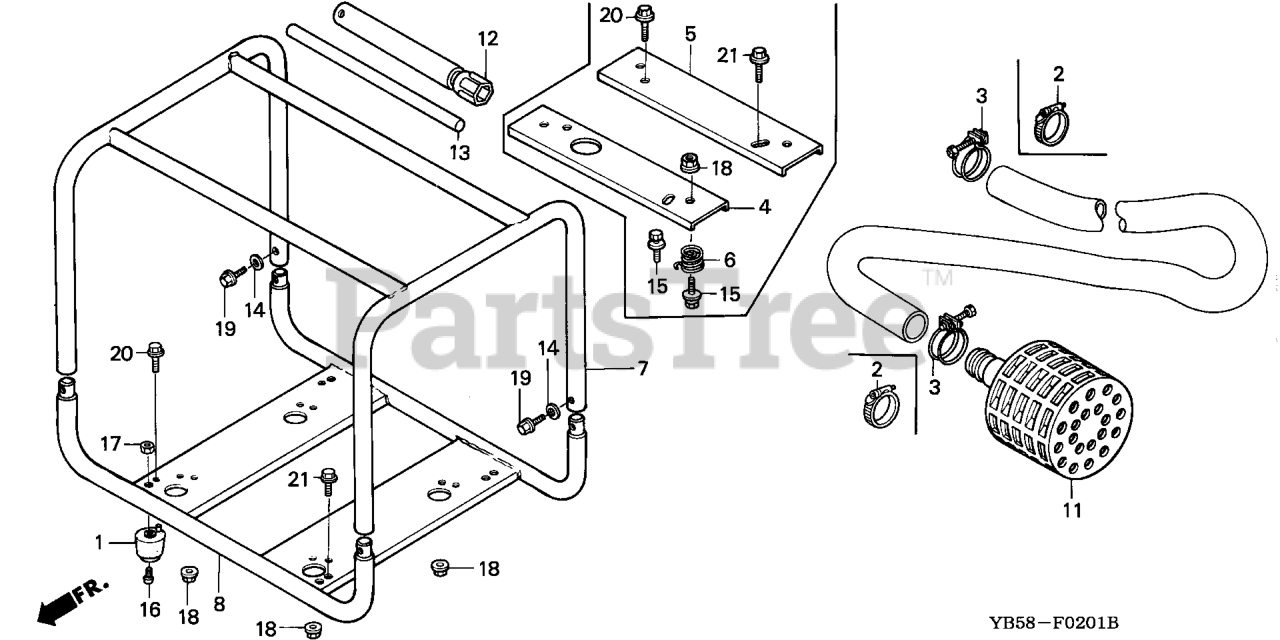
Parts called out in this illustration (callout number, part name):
1	RUBBER (LOWER)
3	BAND, HOSE
4	STAY A, MOUNTING
5	STAY B, MOUNTING
6	SPRING, MOUNT
7	FRAME (UPPER)
8	FRAME (LOWER)
11	STRAINER
12	WRENCH, SPARK PLUG
13	HANDLE, BOX WRENCH (NOT AVAILABLE)
14	WASHER, FRAME JOINT
15	BOLT-WASHER (8X20)
16	SCREW, PAN (6X10)
17	NUT, HEX. (6MM)
18	NUT, FLANGE (8MM)
19	BOLT, FLANGE (8X18) Use from Frame SN 1256673.
20	BOLT, FLANGE (8X25)
21	BOLT, FLANGE (8X28)
